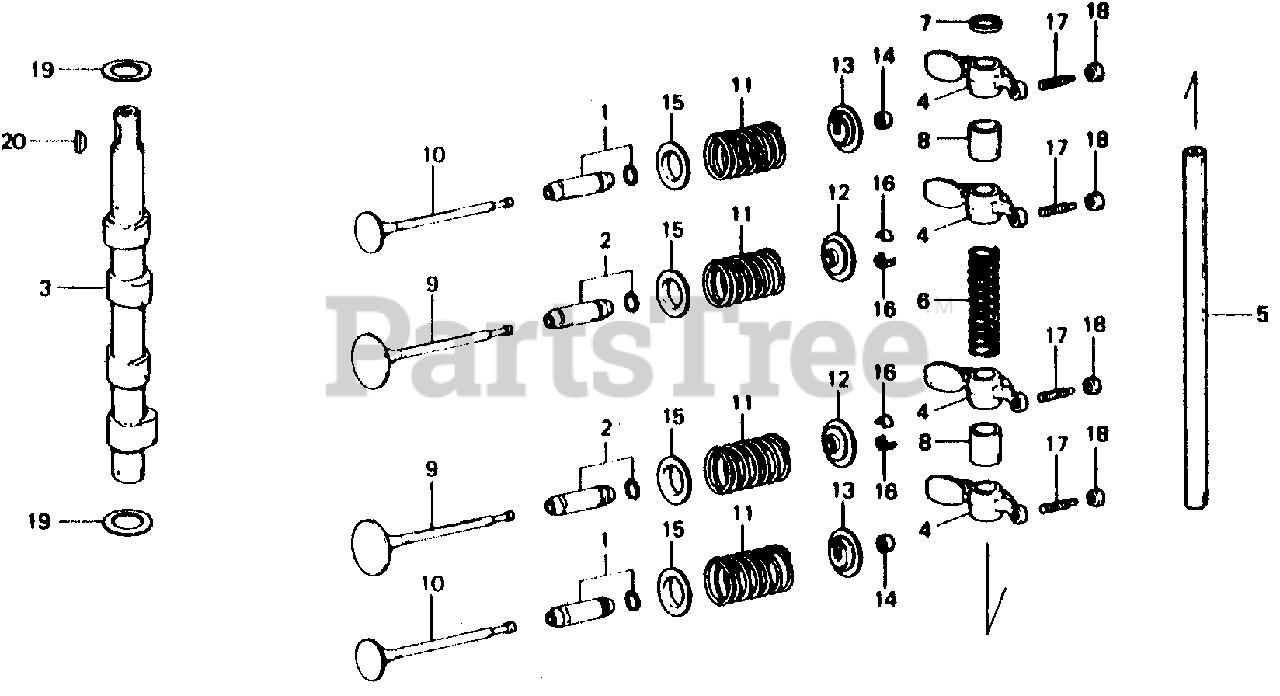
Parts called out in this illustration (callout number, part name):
1	GUIDE, VALVE (NOT AVAILABLE)
2	GUIDE, VALVE (NOT AVAILABLE)
3	CAMSHAFT (NOT AVAILABLE)
4	ARM, VALVE ROCKER
5	SHAFT, VALVE ROCKER ARM
6	SPRING, VALVE ROCKER ARM
7	COLLAR A, VALVE ROCKER ARM
8	COLLAR B, VALVE ROCKER ARM
9	VALVE, IN.
10	VALVE, EX.
11	SPRING, VALVE
12	RETAINER, VALVE SPRING
13	RETAINER, VALVE SPRING
14	ROTATOR, VALVE
15	SEAT, VALVE SPRING
16	COTTER, VALVE (NOT AVAILABLE)
17	SCREW, TAPPET ADJUSTING
18	NUT, TAPPET ADJUSTING
19	WASHER, THRUST (16MM)
20	KEY, WOODRUFF (16X12) (SOURCE: VINTAGE PARTS INC.)
